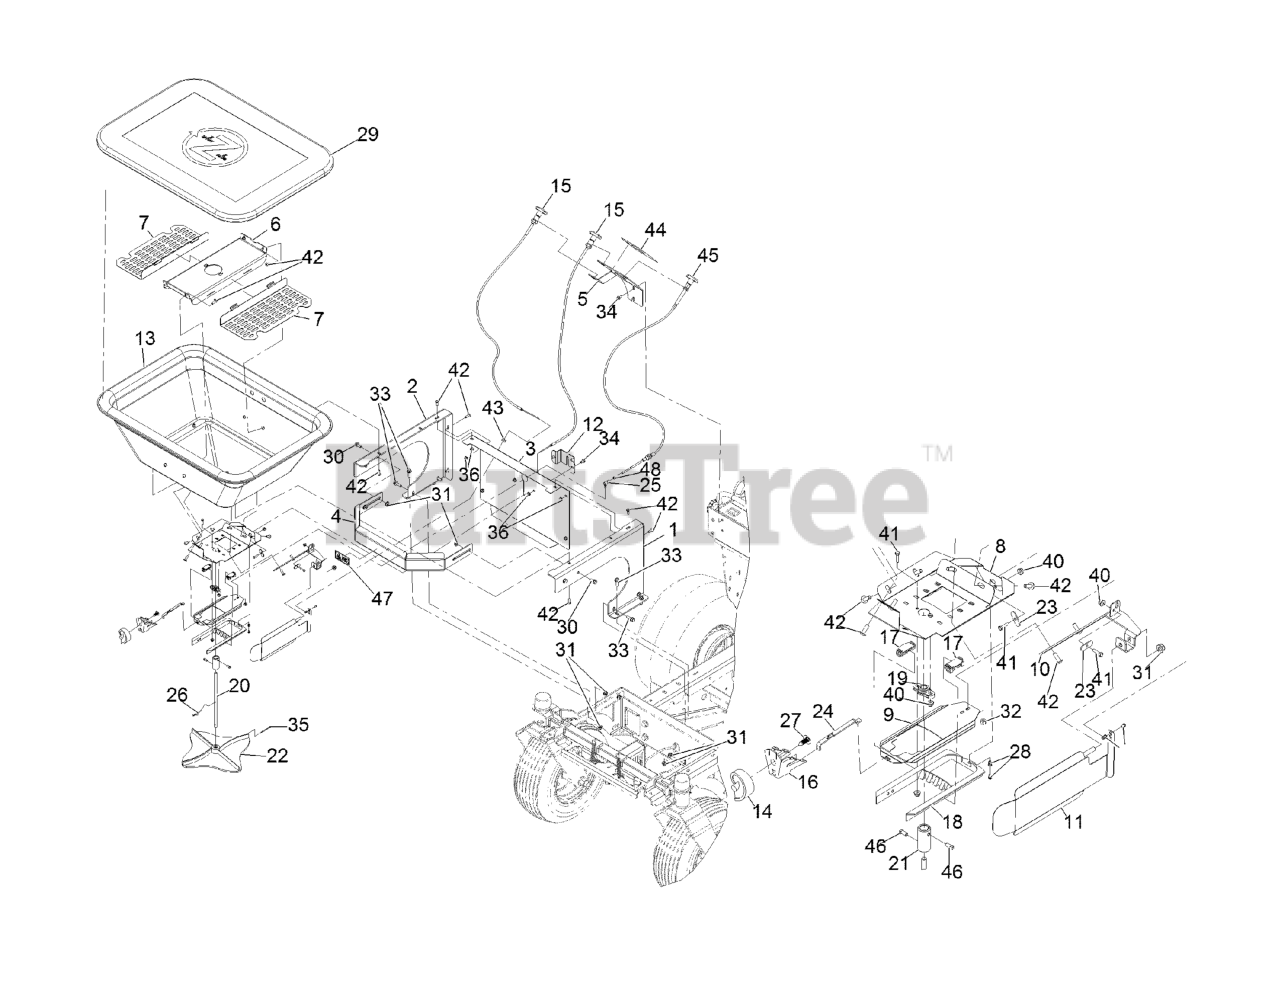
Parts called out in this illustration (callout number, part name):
1	Side-Hopper, Rt
2	Side-Hopper, Lt
3	Backshield-Hopper
4	BUMPER-FRONT, HOPPER
5	Mount-Speedometer
6	Pan-Hopper, 150
7	Screen-Hopper, 150
8	Plate-Base, Hopper
9	Door-Slide, Hopper
10	Mount-Deflector, Side
11	Deflector-Side, Spreader
12	Bracket-Hopper, 150 Cable Offset
13	Hopper-150Lb
14	DIAL
15	CABLE-PUSH/PULL
16	MOUNT-DIAL
17	GUIDE-RATE, GATE
18	DIFFUSER
19	BEARING-FLANGE
20	Shaft-Hopper, 150
21	COUPLER-SS
22	SPINNER-SPREADER
23	RETAINER, CABLE
24	LINKAGE-GATE, RATE
25	BALL JOINT-SS
26	WIRE-AGITATOR
27	CLIP
28	RETAINER-CABLE, WIRE
29	COVER-HOPPER, LARGE
30	SCREW-HHF
31	Nut-Hex Flange
32	Nut,NYL Lock,#10-32,ST/ST 18-8
33	SCREW-HHF
34	SCREW-HHF
35	PIN-COTTER
36	Nut-Hex Flange
40	Nut-Hex Flange
41	SCREW-HH
42	Screw-Hsbhf
43	Grommet-Rubber
44	DECAL-HOPPER CONTROL
45	CABLE-PUSH/PULL
46	Screw-SQH
47	Decal-Dismemberment Hazard
48	Nut,Hex Jam Mch Scr,10-32,Sst
